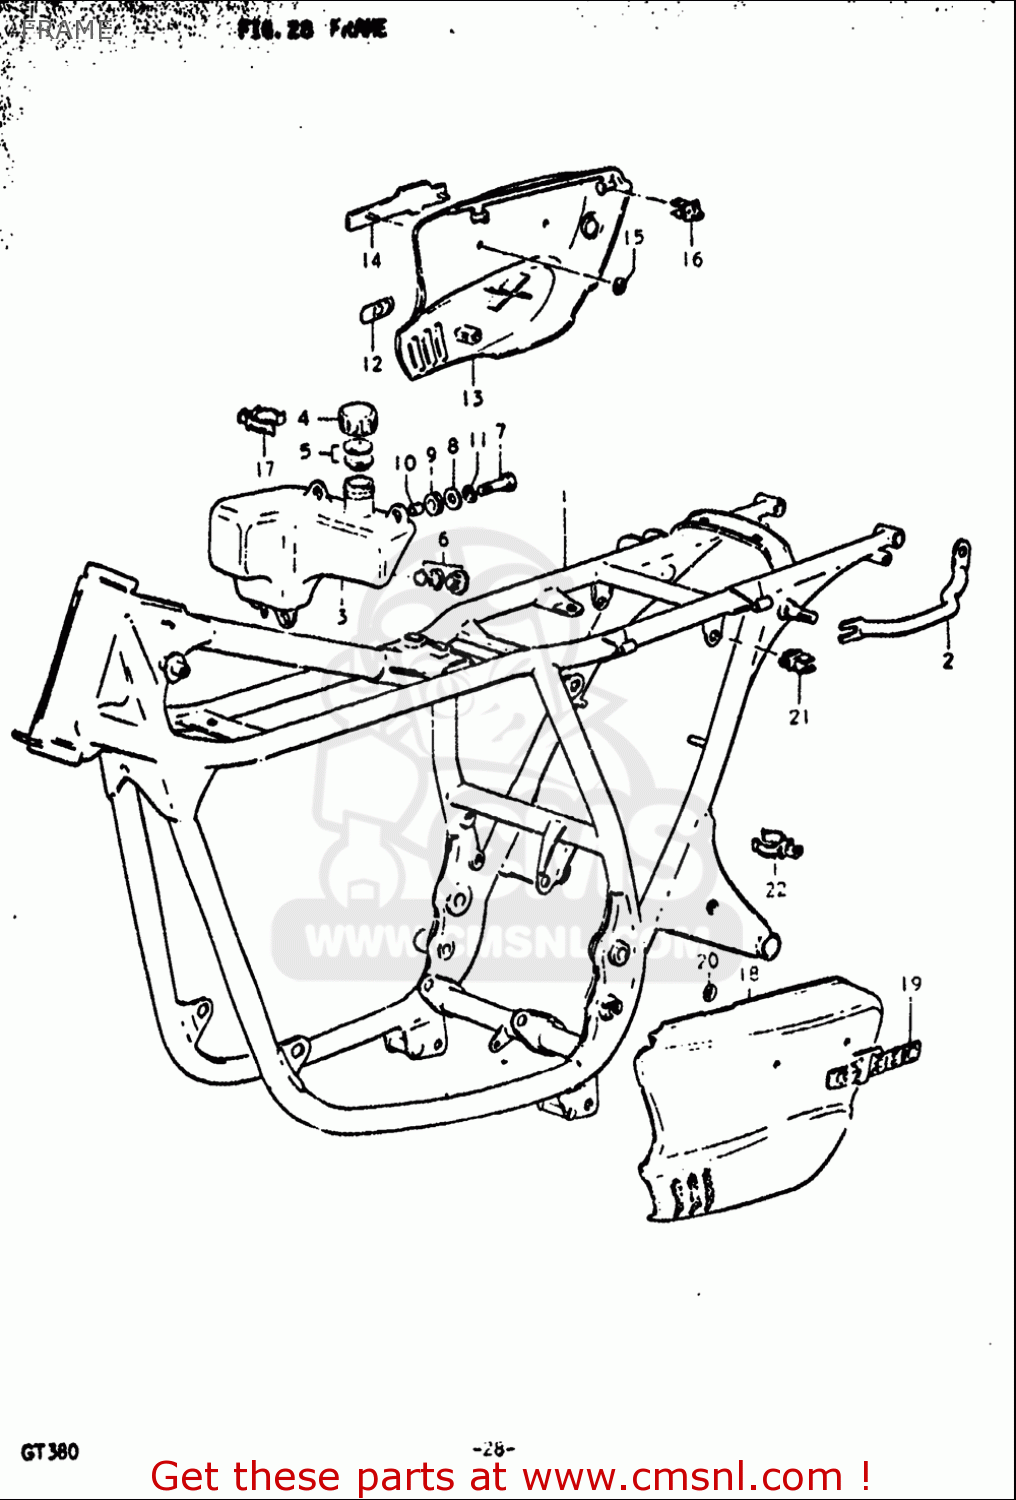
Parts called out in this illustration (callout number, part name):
4	CAP,OIL TANK
5	GASKET SET (NAS)
6	LENS SET,OIL LEVEL
7	BOLT
8	WASHER(6.5X18X1.6)
9	CUSHION
10	SPACER(6.5X10X10)
11	WASHER,LOCK
12	EMBLEM,CCIS
13	COVER,FRAME,R(BLACK)
14	EMBLEM,FRAME COVER,L
15	NUT
19	EMBLEM,FRAME COVER,L
20	NUT
